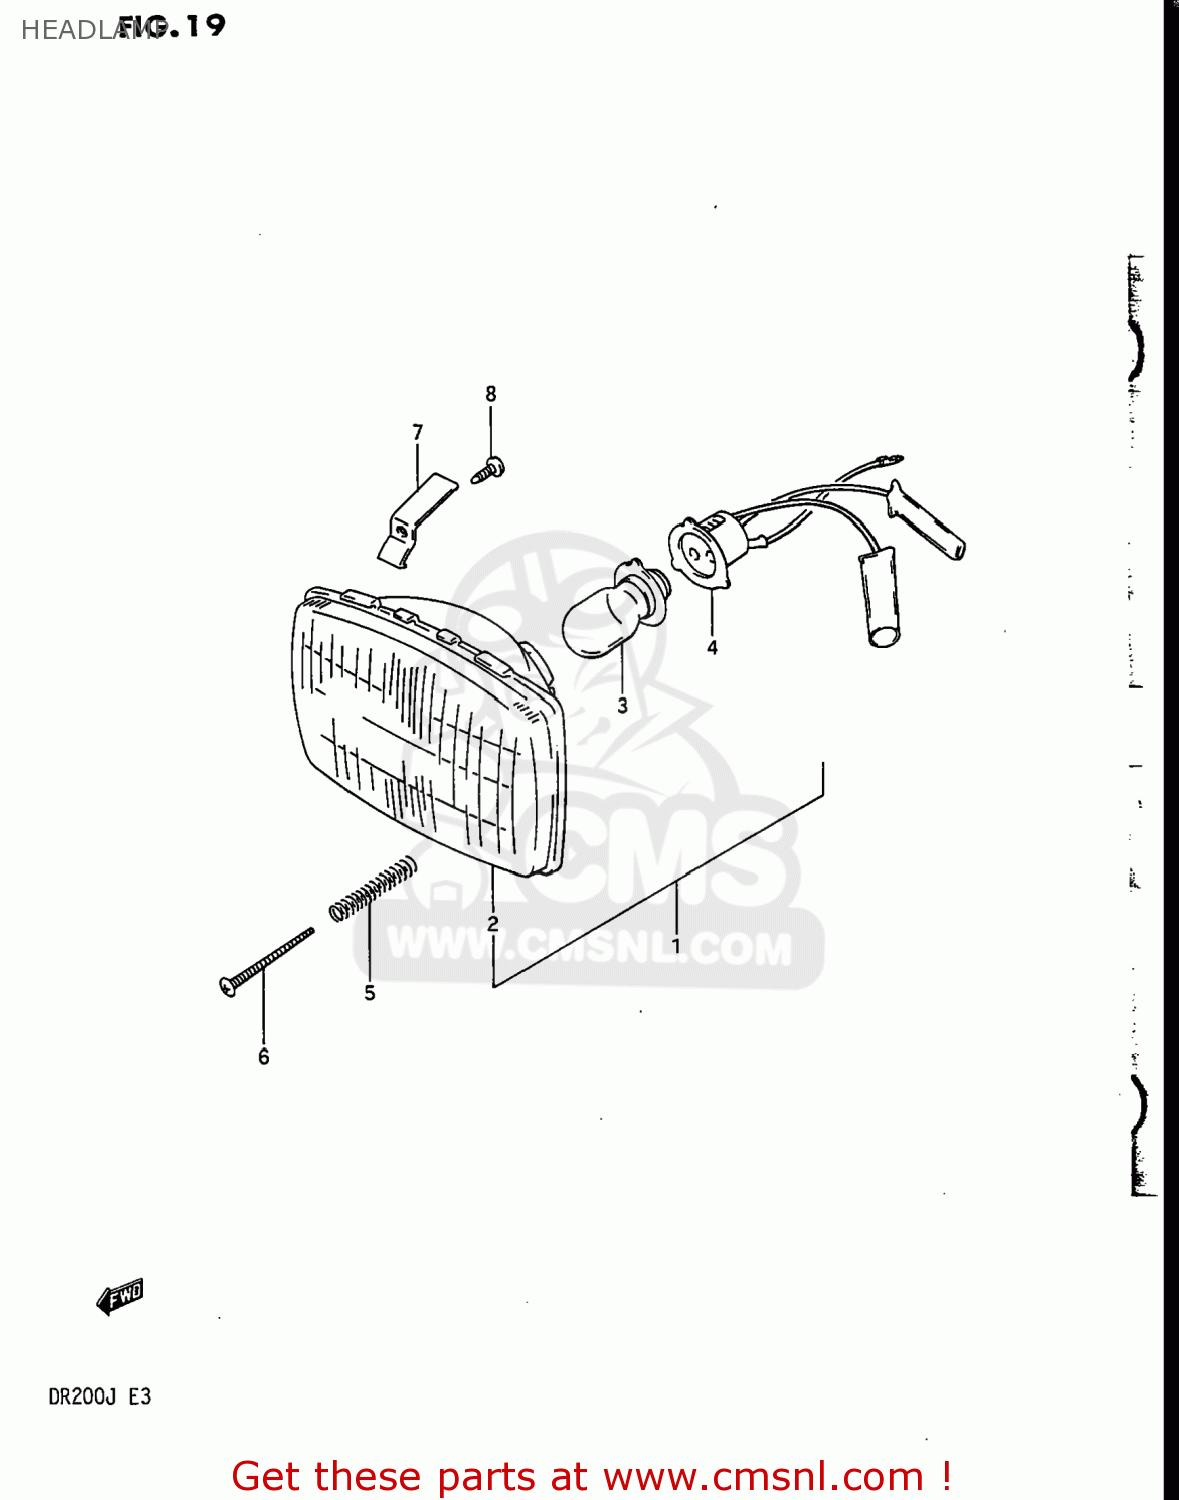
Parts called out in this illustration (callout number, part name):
1	HEADLAMP ASSEMBLY
2	LAMP UNIT
3	BULB
4	SOCKET,HEADLAMP
5	SPRING,HEAD LAMP ADJUSTER
6	SCREW,HEADLAMP ADJUST
7	SPRING
8	SPRING,HEADLAMP ADJUST
